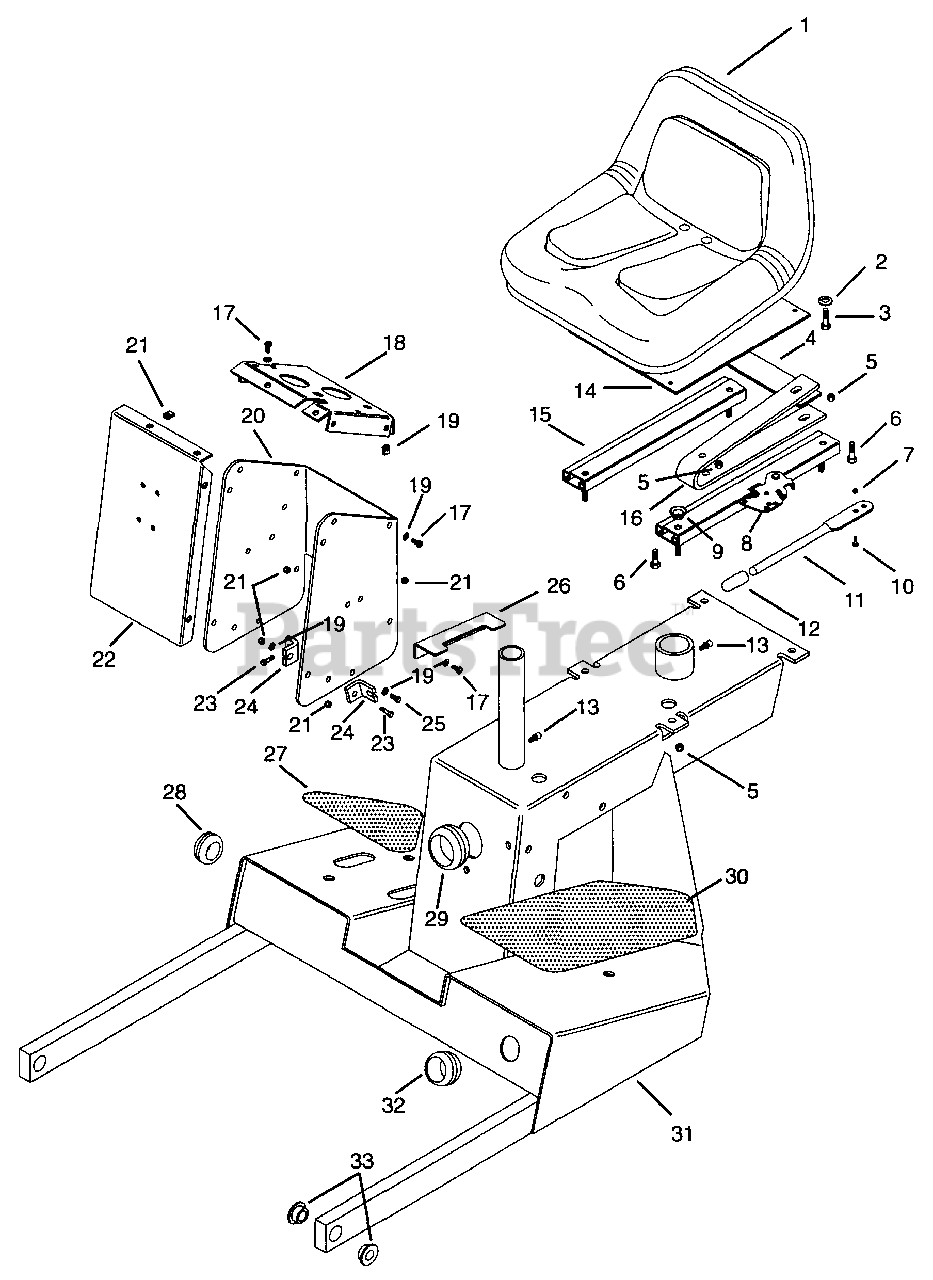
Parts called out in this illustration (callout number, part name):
1	Seat High Back
2	Washer-Lock .31 x .078
3	Bolt-Hex .31-18 x 1.00 Grade 5
4	Bracket, Seat
5	Nut-Locking-Center .31-18
6	Bolt-Hex .38-16 x 1.25 Grade 5
7	Nut-Locking Nylon 10-24 W/Insrt
8	Adjuster, Seat w/Latch
9	Seat Slide Spacer
10	Screw-Machine 10-24 x .50
11	Seat Slide Handle
12	Tip-Brake Lock Lever
13	Fitting-Lube .25-28 x .256
14	Plate
15	Adjuster, Seat
16	Spring, Seat
17	Screw-Machine .25-20
18	Panel, Instrument
19	Nut-Retainer .25-20 x .56
20	Support, Panel
21	Nut-Locking-Center .25-20
22	Cover, Panel
23	Bolt-Hex .25-20 x 1.00 Grade 5
24	Bracket, Cable
25	Bolt-Hex .25-20 x .75 Grade 5
26	Stop, Brake Lever
27	Cover, Footboard Left Hand
28	Grommet 1.25 x 1.5 x 1.81
29	Grommet
30	Cover, Footboard Right Hand
31	Weldment, Rear Frame
32	Grommet 1.50 x 1.75 x 2.12
33	Bushing-Flange .762 x 1.0 x .580 x 1.48
